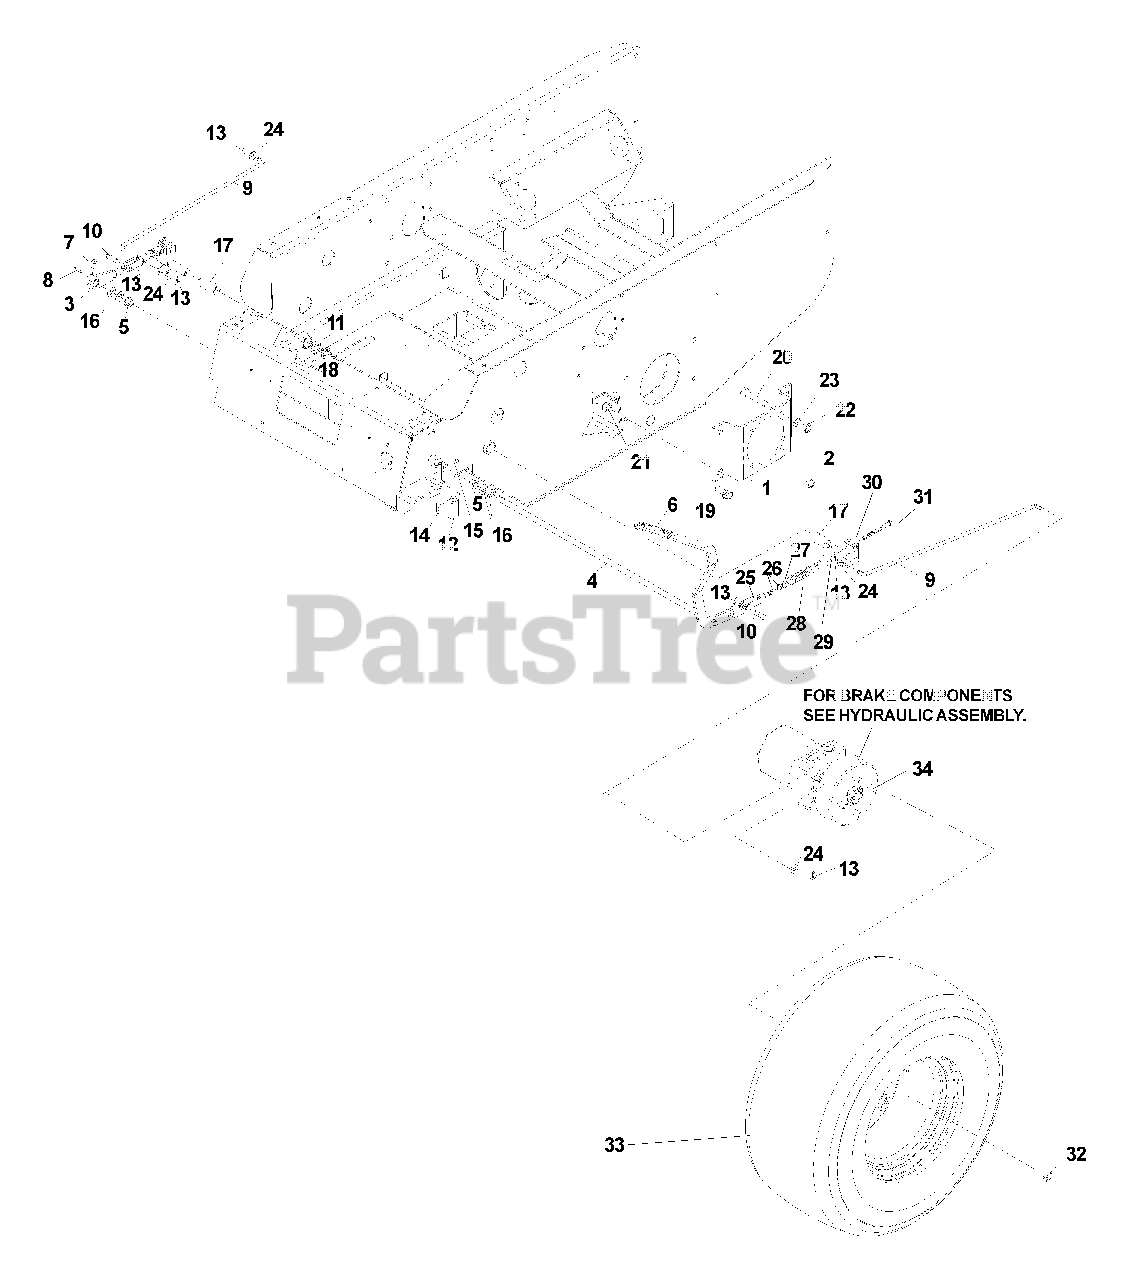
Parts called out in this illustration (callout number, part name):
1	Standoff, wheel motor
2	Nut, 1/2, lug
4	Brake lever
5	Bushing, bronze
6	Grip, park brake
7	Setscrew, 5/16-18 sq. x 5/8
8	Key, 1/8 sq. x 7/8
9	Brake linkage bar
10	Pin, clevis
11	Bushing, machine, 3/4
13	Pin, cotter
14	Plate, tapped
15	Screw, #10-24 x 5/8
16	Washer, 7/16, spring
17	Bearing, bronze
18	E-ring, 3/4
19	Bolt, 1/2-13 x 1 1/4, serrated washer
20	Bolt, 1/2-13 x 2 3/4
21	Nut, 1/2-13, nyloc
22	Nut, 1/2-13
23	Lockwasher, 1/2
24	Washer, 5/16
26	Nut, 3/8-24
27	Washer 3/8
29	Pin, trunion
31	Bolt, 3/8-24 x 4 1/2, special
32	Nut, 1/2, lug
33	Tire, rear, assembly
34	Wheel stud, 1/2-20 x 1 3/8, Gr8
